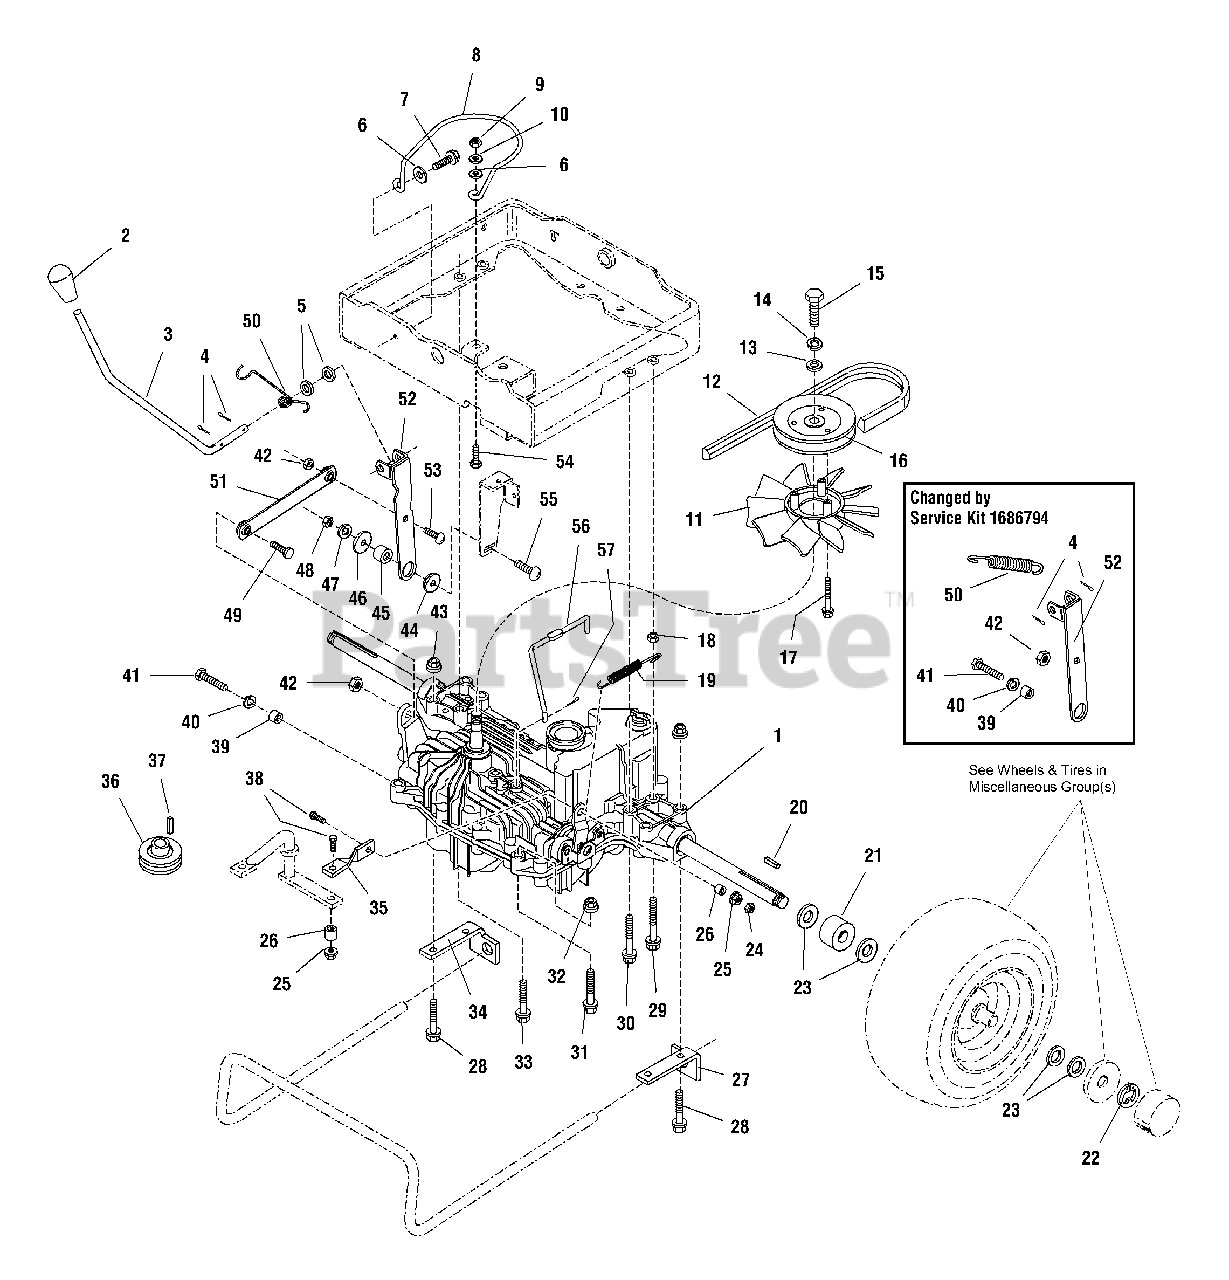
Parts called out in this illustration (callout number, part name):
1	TRANSMISSION ASSEMBLY
2	KNOB, Plastic, Gear Shift
4	PIN, Cotter, 3/32 x 1
5	WASHER, 1/2
6	WASHER, Plain, 5/16
7	CAPSCREW, Taptite Hex Washer Hd, 5/16-18 x 3/4
8	GUIDE, Belt
9	NUT, Hex, Full, 5/16-18
10	LOCKWASHER, 5/16
12	BELT, Drive
13	WASHER, 1/4
14	LOCKWASHER, 1/4
15	CAPSCREW, Hex Hd, M06 - 1.00 x 30mm
16	PULLEY & HUB ASSEMBLY
17	CAPSCREW, Taptite Hex Washer Hd, 1/4-20 x 1-1/2
18	JAM NUT, Top Lock, 5/16-18
19	SPRING, Brake Return
20	KEY
21	SPACER
22	E-RING
23	WASHER, 3/4
24	LOCK NUT, Center, 1/4-20
25	NUT, Hex Flange Lock, 1/4-20
27	ANCHOR, Torsion Bar, L.H.
28	CAPSCREW, Whiz Lock Hex Hd, 5/16-18 x 2-1/2
29	CAPSCREW, Taptite Hex Washer Hd, 5/16-18 x 3-1/2
30	CAPSCREW, Taptite Hex Washer Hd, 5/16-18 x 3
31	CAPSCREW, Whiz Lock Hex Hd, 5/16-18 x 1-1/4
32	NUT, Hex, Flange Whiz Lock, 5/16-18
33	CAPSCREW, Taptite Hex Washer Hd, 5/16-18 x 2-1/2
34	ANCHOR, Torsion Bar, R.H.
36	PULLEY ASSEMBLY, Engine PTO
37	KEY, Hi-Pro
38	CAPSCREW, Hex Hd, 1/4-20 x 1
40	LOCKWASHER, Spring, 7/16
41	CAPSCREW, Hex Hd, M10-1 1/2 x 25MM
42	NUT, Hex Flange Lock, 5/16-18
43	NUT, Hex Flange Whiz-Lock, 5/16-18
44	WASHER, 3/8
46	WASHER, 3/8
47	LOCKWASHER, 3/8
48	NUT, ESNA Hex Lock, 3/8-16
49	CAPSCREW, Hex Hd, 5/16-18 x 1-1/4
50	SPRING, Return
50	SPRING, Torsion
51	LINK, Lower Shift
52	LEVER & CLEVIS ASSEMBLY
53	CARRIAGE BOLT, 5/16-18 x 1
54	CAPSCREW, Hex Hd, 5/16-18 x 1
55	CARRIAGE BOLT, 3/8-16 x 1-1/4
56	ROD, Transmission Release
57	PIN, Cotter, 3/32 x 3/4
